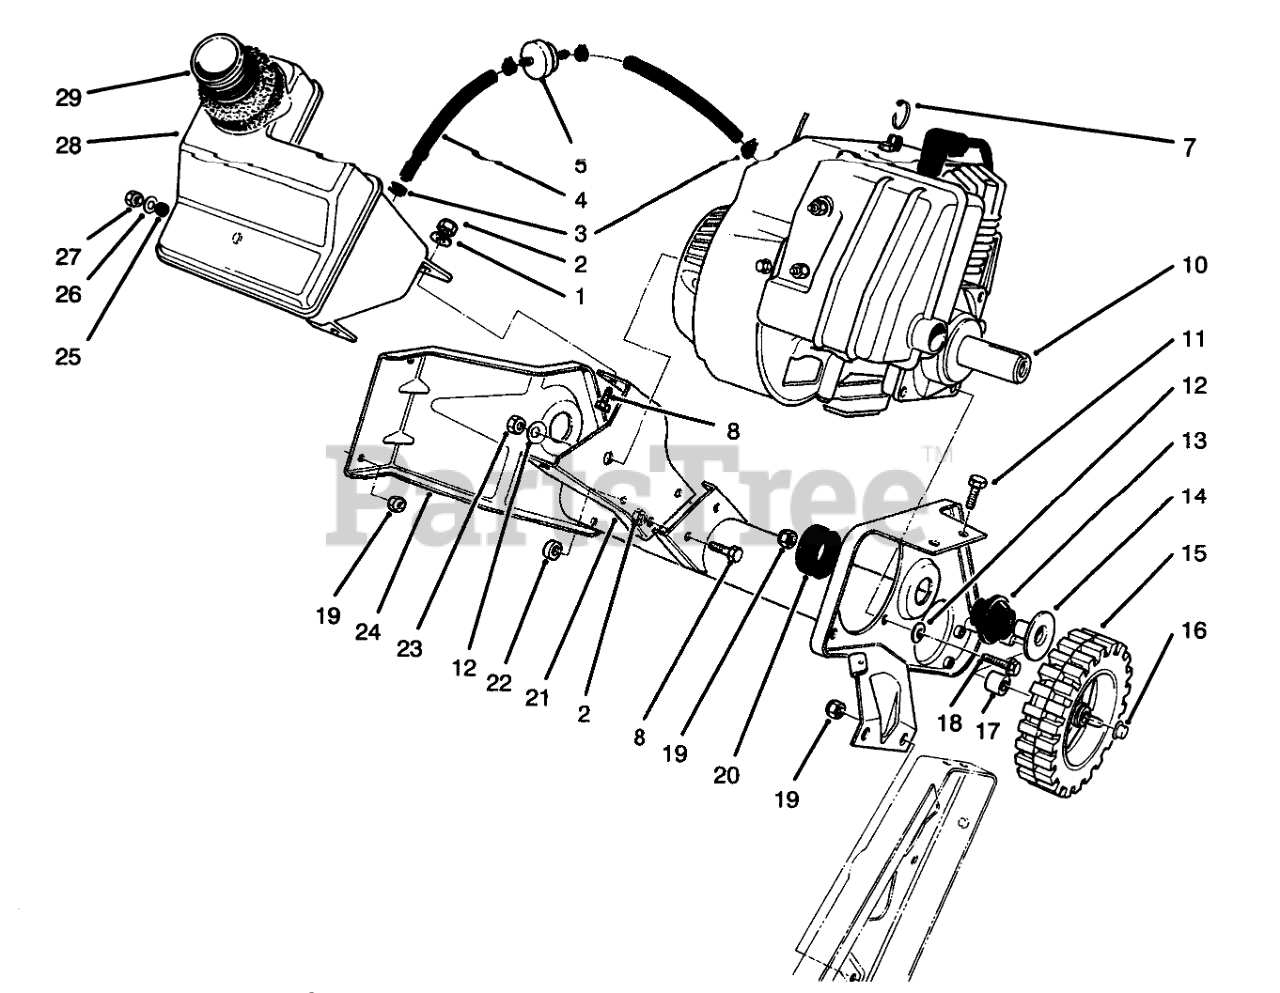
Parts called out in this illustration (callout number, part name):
1	WASHER-FLAT
2	NUT-LOCK, NI
3	CLAMP-HOSE
4	GAS LINE
5	FILTER-FUEL
7	TIE-CABLE
8	SCREW-HH
10	Engine Assembly
11	SCREW-HH
12	WASHER-BELLEVILLE
13	MOUNT-REBOUND
14	SPACER TUBE
15	WHEEL
16	NUT-PUSH
17	SPACER-WHEEL
19	NUT-LOCK, NI
20	LOAD MOUNT
21	Support-Recoil
22	SPACER-WHEEL
23	NUT (F/W & PPP)
24	Wa-Frame
25	GROMMET-RUBBER
26	WASHER-PLAIN
27	NUT-LOCK, CONE
28	Tank-Fuel (Incl. Ref. #25)
29	SEAL-FOAM
